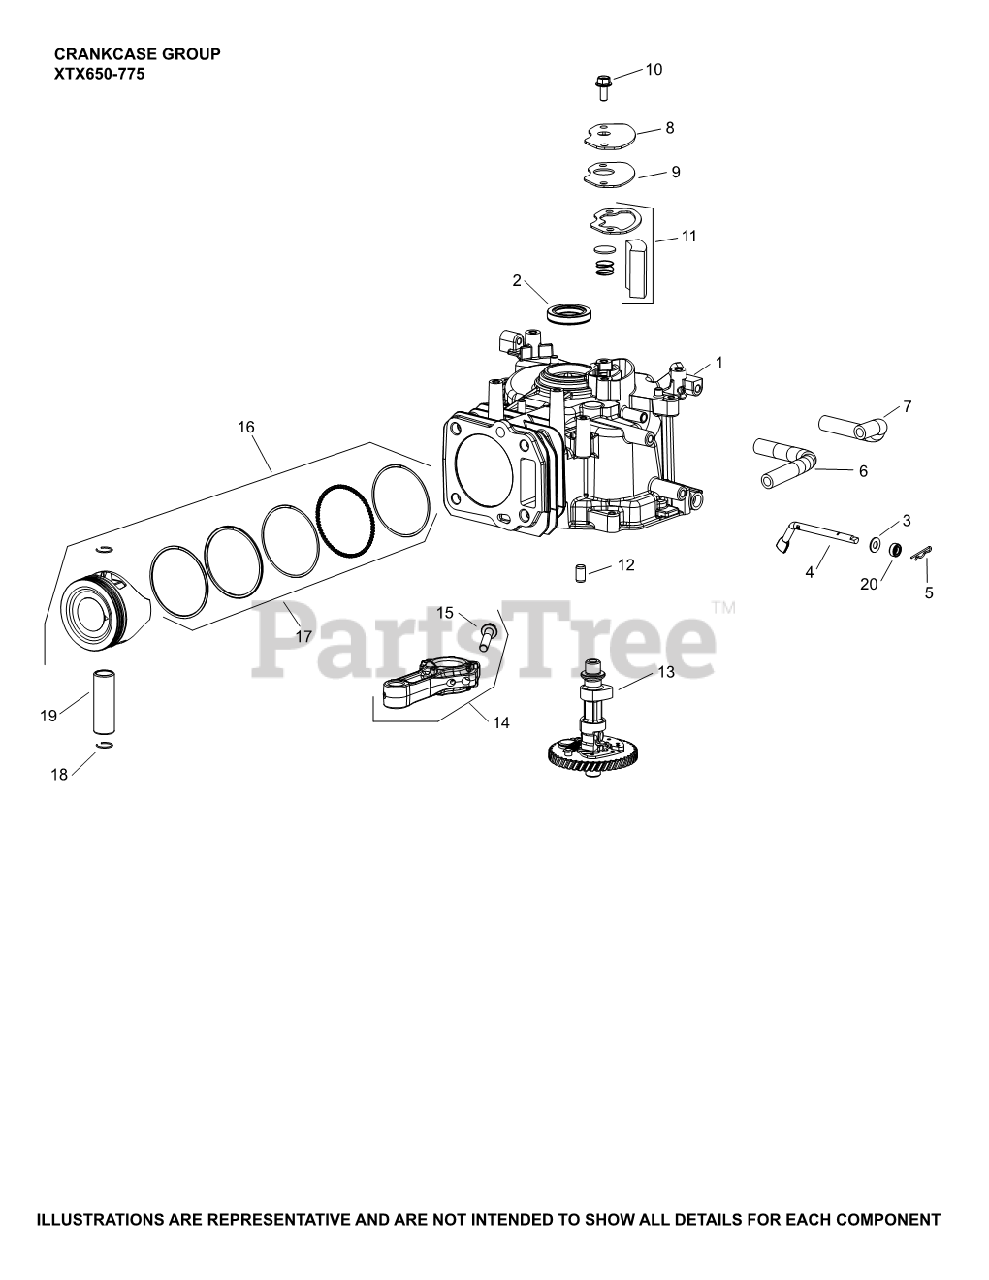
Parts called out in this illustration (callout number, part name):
1	CRANKCASE
2	SEAL, CCASE/FLYWHEEL
3	WASHER, FLAT (DIA 13MM O.D.)
4	SHAFT, GOVERNOR CROSS
5	CLIP, GOVERNOR SHAFT
7	HOSE, BREATHER
8	COVER, BREATHER
9	GASKET, BREATHER COVER
10	SCREW, HEX FLANGE (M6)-USE 25 086 433-S
11	KIT, BREATHER FILTER
12	PIN, DOWEL (8MM)
13	CAMSHAFT ASSEMBLY
14	CONNECTING ROD
15	SCREW, HEX FLANGE (M7) (CKY)
16	KIT, PISTON
18	RETAINER, PISTON PIN
19	PIN, PISTON
20	SEAL, OIL
